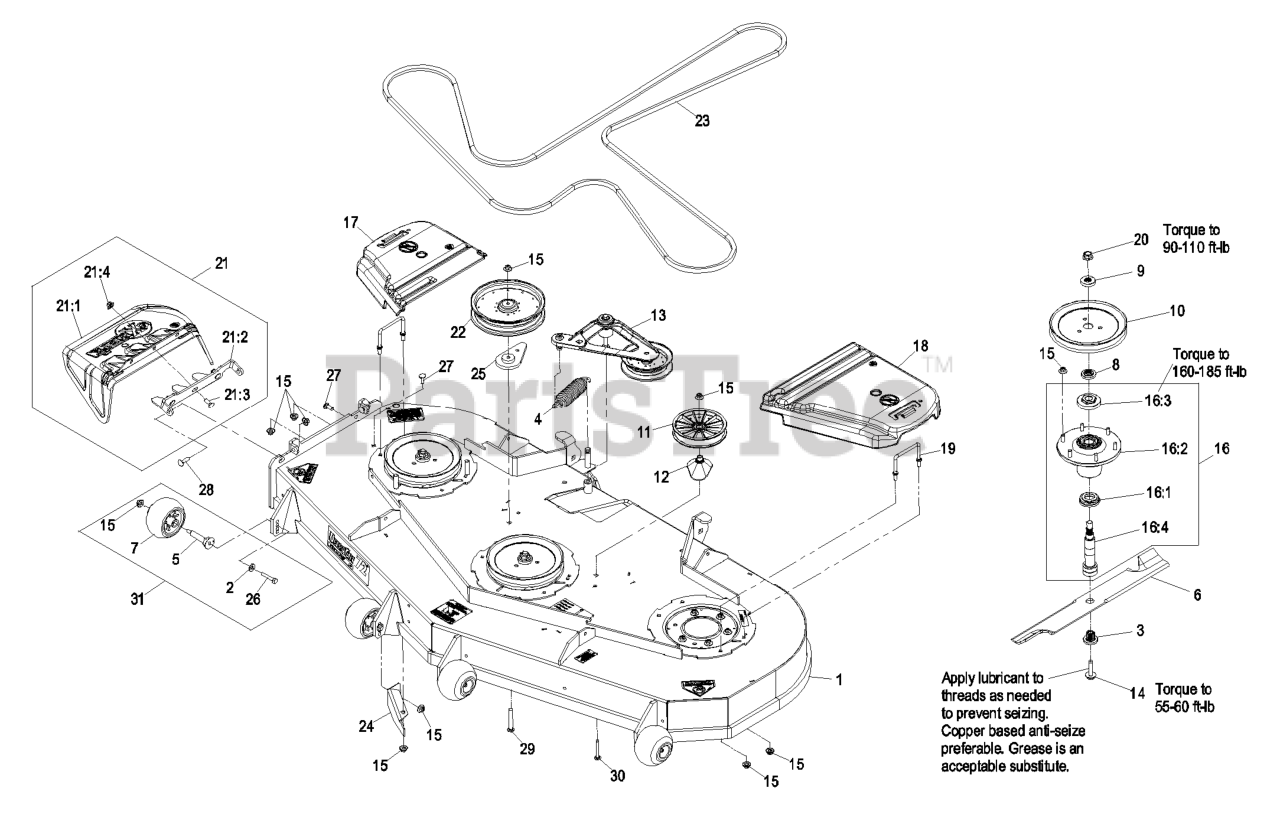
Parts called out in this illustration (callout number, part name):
1	DECK W/ DECALS ASM-72
2	WASHER-BELLEVILLE
3	BUSHING,SPLINED
7	ROLLER-SCALP, ANTI
8	SPACER,SPLINED STEPPED
9	SPACER,SPLINED
10	SHEAVE,BLADE DRIVE 9.00
11	PULLEY,IDLER 6"
12	SPACER-PULLEY
14	SCREW,SEMS 1/2-20 X 2.19
15	Nut-Nyloc 3/8-16 Flg
16	ASM,SPINDLE HOUSING
16:1	GUARD,BOTTOM
16:2	ASM,CUTTER HOUSING
16:3	NUT, SPINDLE 7/8-14
16:4	SPINDLE,DOUBLE SPLINE
17	COVER-BELT, RH
18	COVER-BELT, LH
19	WIREFORM-COVER
20	NUT-FLANGE, CENTERLOCK
21	ASM,DISCHARGE CHUTE
21:1	CHUTE,DISCHARGE
21:2	BRACKET,DISCHARGE CHUTE
21:3	SCREW-CARR
21:4	Nut-Nyloc 3/8-16 Flg
22	PULLEY-IDLER
23	BELT-V
24	BAFFLE,DISCHARGE 726
25	SPACER-IDLER
26	SCREW-HH
27	SCREW-CARR
28	Bolt-Carriage 3/8-16 X 1 1/4
29	SCREW-CARR
30	SCREW-CARR
32	Asm, Deck Complete 726
